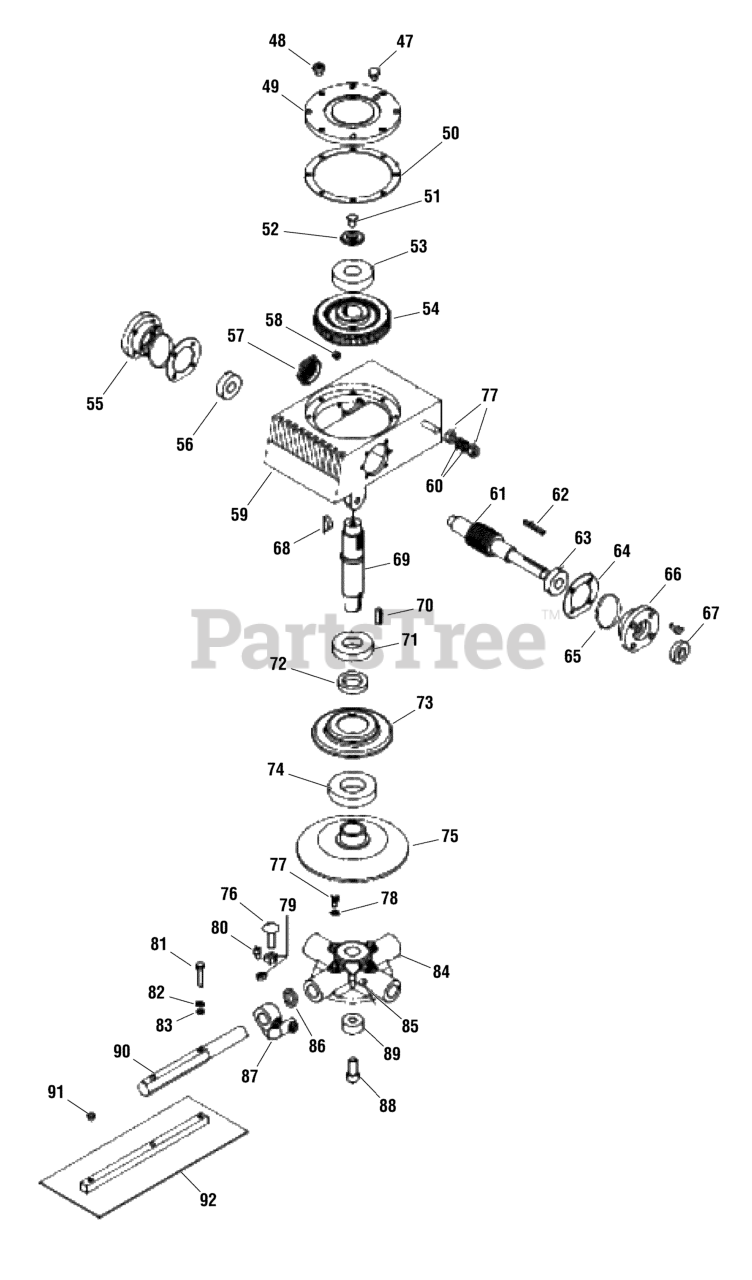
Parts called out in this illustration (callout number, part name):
47	REDUCING VALVES
48	SCREW, Set, M6 x 15
49	COVER, Gear Box
50	GASKET, Plastic
51	SCREW, Cross Recessed Countersunk Head, M10 x 25 (left)
52	RING, Clamping
53	ROLLER BEARING, Tapered, 30305
54	WORM WHEEL
55	RIGHT BEARING BLOCK
56	DGBB 6004
57	OIL LEVELER
58	PLUG, Hex Socket Head, ZG3/8?-19
59	GEAR BOX
60	WASHER, Pain, d10
62	KEY, B5 x 30
63	ROLLER BEARING, Tapered, 32004
64	GASKET, Plastic
65	O-RING, 48.7 x 3.5
66	BEARING BLOCK, Left
67	OIL SEAL, FB20-40-10
68	KEY, Woodruff
69	SHAFT, Worm Wheel
70	KEY, B6 x 30
71	DGBB 6206
72	OIL SEAL, FB27-47-10
73	COVER, Platen
74	DGBB 6009
75	PLATEN
76	BOLT, Carriage, M10 x 35
77	BOLT, Hex, M10 x 20
78	WASHER, Spring, d10
79	NUT, M10
80	BOLT, Set, Square Head, M10 x 30
81	BOLT, Hex, M8 x 40
82	WASHER, Spring, 8
83	WASHER, Flat, d8
84	CROSS BASE
85	FITTING, Grease, ZG1/8x28
86	OIL SEAL, 21.8 x 2.40
88	BOLT, Hex Socket Head, M10 x 30
89	PACKING SET
90	SHAFT, Hexagonal Adjust
91	PP PLUG
92	BLADE ASSEMBLY
